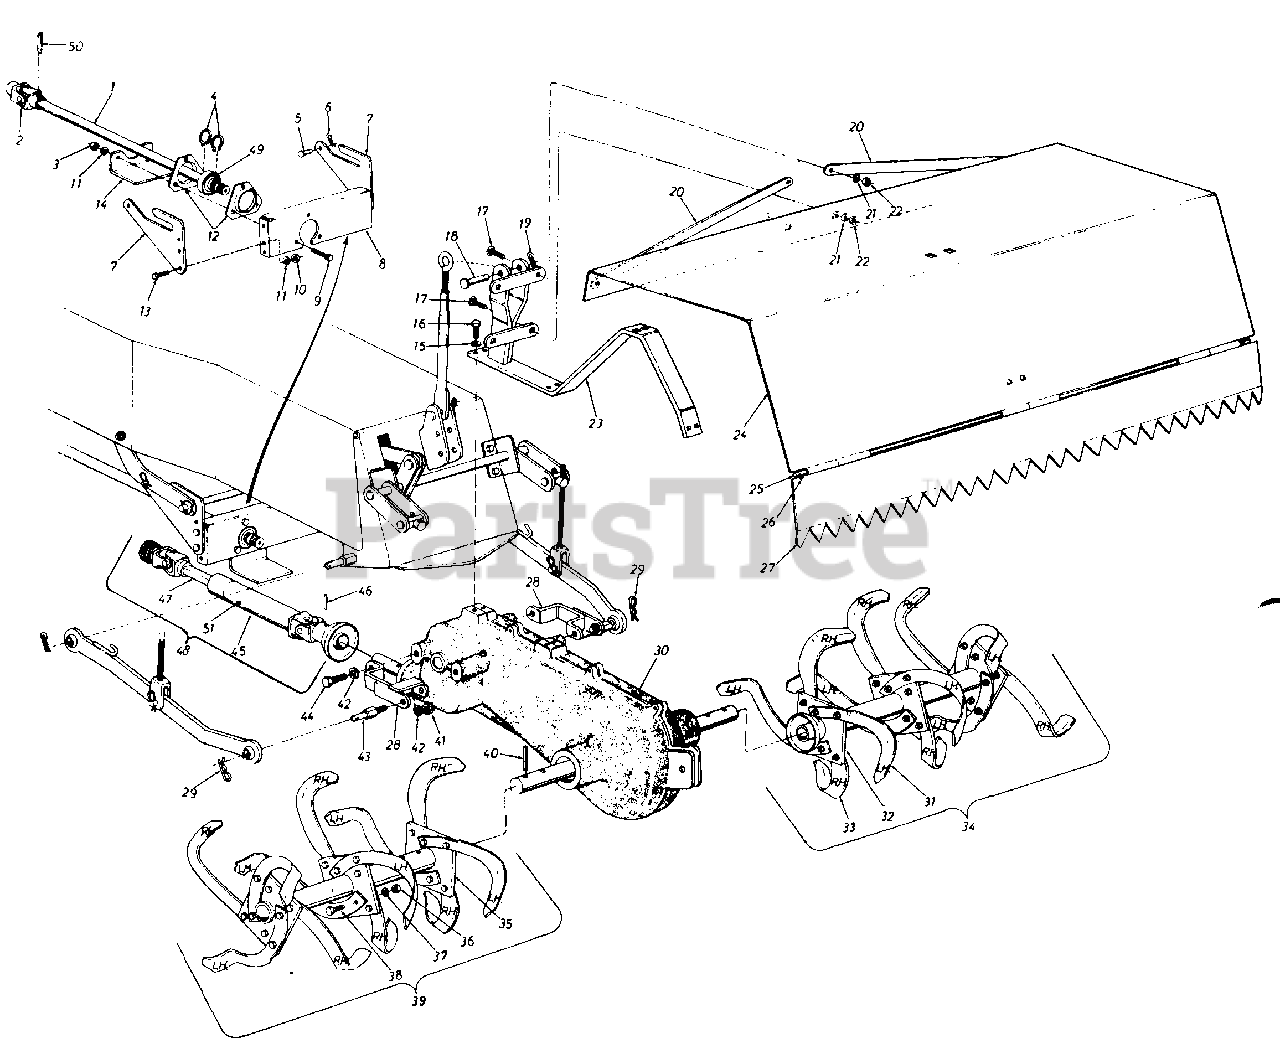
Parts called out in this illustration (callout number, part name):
1	Universal Drive Shaft Ass'y.
2	Universal Joint
3	Hex Nut 5/16-24 Thd.
4	Retaining Ring 1.00" Dia. Shaft
5	Clevis Pin
6	Internal Cotter Pin
7	Hanyer Bracket
8	Drive Shaft Brg. Support Brkt.
9	Carriage Bolt 5/16-18 x 1.00" Lg. *
10	Hex Nut 5/16-18 Thd.*
11	L.-Wash. 5/16" Scr.*
12	Flangette-1" Dia. Shaft
13	Hex Scr. 5/16-24 x .75" Lg.*
14	Bearing Brkt. Guard
15	L.-Wash. 1/2" Scr.*
16	Hex Scr. 1/2-13 x 1.25" Lg.*
17	Carriage Bolt 5/16-18 x 1.00 Lg.*
18	Clevis Pin 5/8" Dia. x 2.4" Lg.
19	Internal Cotter Pin 5/8" Dia.
20	Tiller Cover Strap
21	L.-Wash. 5/16" Scr.*
22	Hex Nut 5/16-18 Thd.*
23	Cover Brkt. Ass'y.
24	Tiller Cover Ass'y.
25	Cover Flap Rod
26	Cotter Pin 1/8" Dia. x 1.00 Lg. *
27	Cover Flap Ass'y.
28	Tiller Pivot Brkt. Ass'y.
29	Internal Cotter Pin 5/8" Dia.
30	Gear Box Ass'y.-Comp.
31	14" Tine-L.H.
32	Mounting Adapter-R.H.
33	14" Tine-R.H.
34	Right Hand Tine Ass'y.-Comp.
35	Mounting Adapter-L.H.
36	Hex Nut 3/8-24 Thd.*
37	L.-Wash. 3/8" Scr.*
38	Hex Scr. 3/8-24 x 1.25" Lg.*
39	Left Hand Tine Ass'y.-Comp.
40	Spring Pin Spirol 3/8" Dia. x 2.00" Lg.
41	Hex Cent. L-Nut 5/8-18 Thd.
42	L.-Wash. 5/8" Scr.*
43	Link Clevis Pin
44	Hex Scr. 5/8-18 x 1.50" Lg.*
45	Universal Drive Shaft-Female Ass'y.
46	Spring Pin Spirol 5/16" Dia. x 1.75" Lg.
47	Universal Drive Shaft-Male Ass'y.
48	Universal Drive Shaft Ass'y.
49	Ball Bearing 1.0" I.D.
50	Spring Pin Spiral 5/16" x 2.50" Lg.
51	Spring Pin Spiral 1/4" Dia. x 1.00" Lg.
